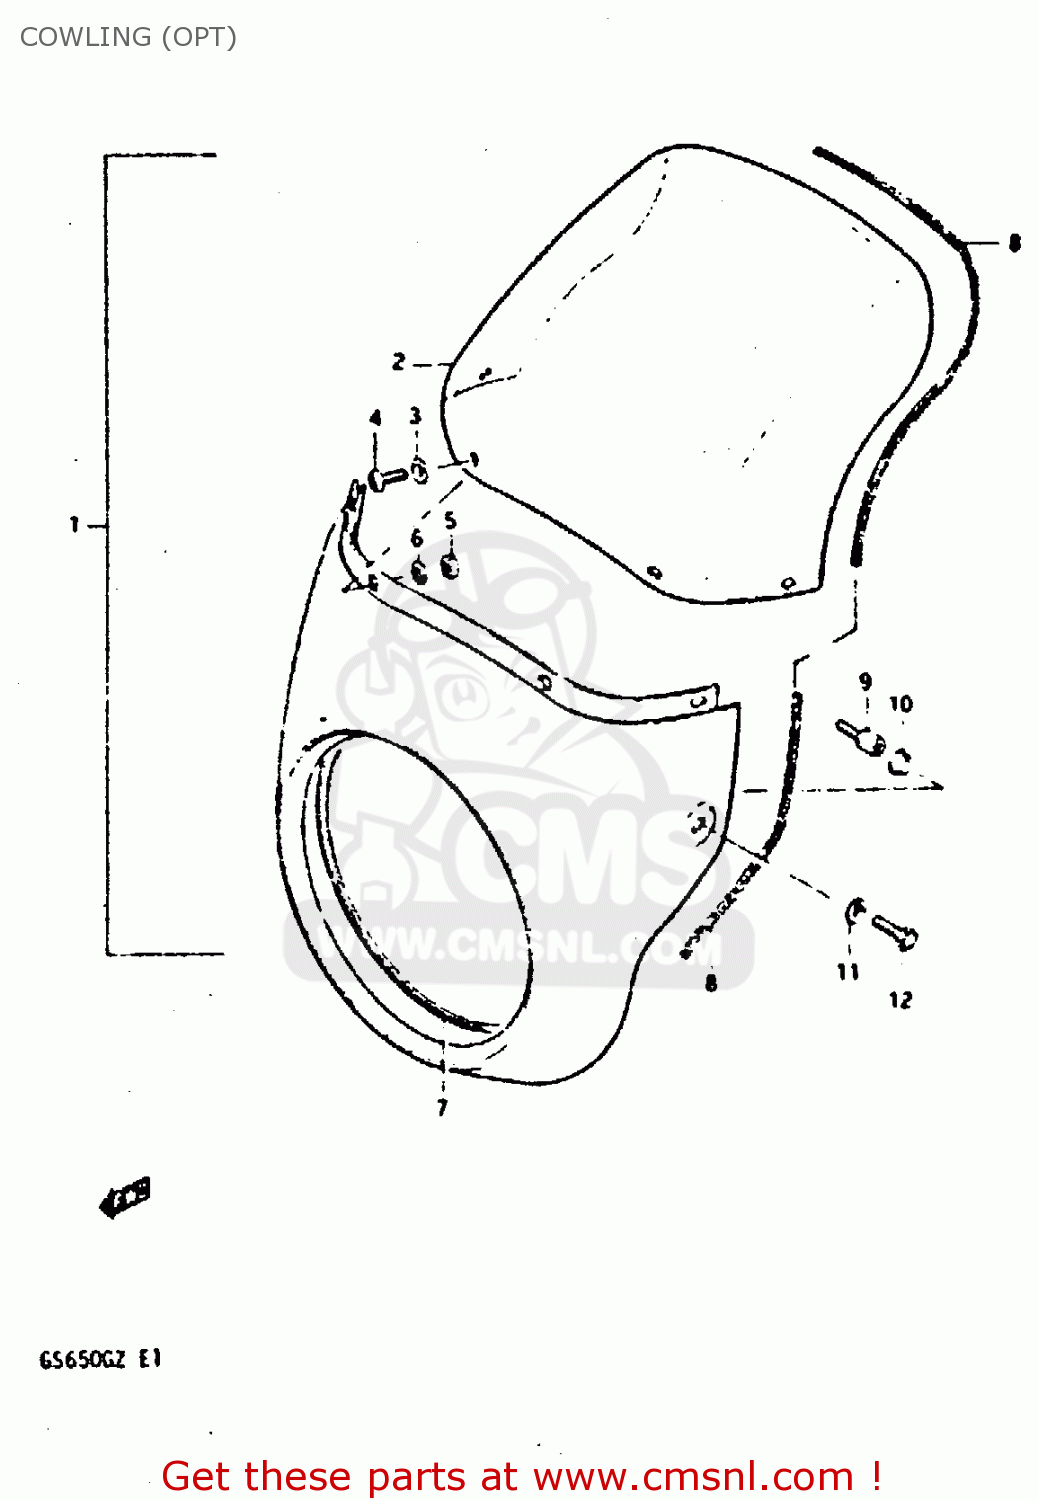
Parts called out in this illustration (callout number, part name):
1	COWLING ASSEMBLY,BODY
2	WINDSCREEN
3	CUSHION
4	SCREW
5	NUT
6	WASHER
7	MOLDING,COWLING
8	MOLDING
9	HOUSING,HEADLAMP
10	WASHER
11	WASHER(6.5X16X1.2)
12	BOLT
